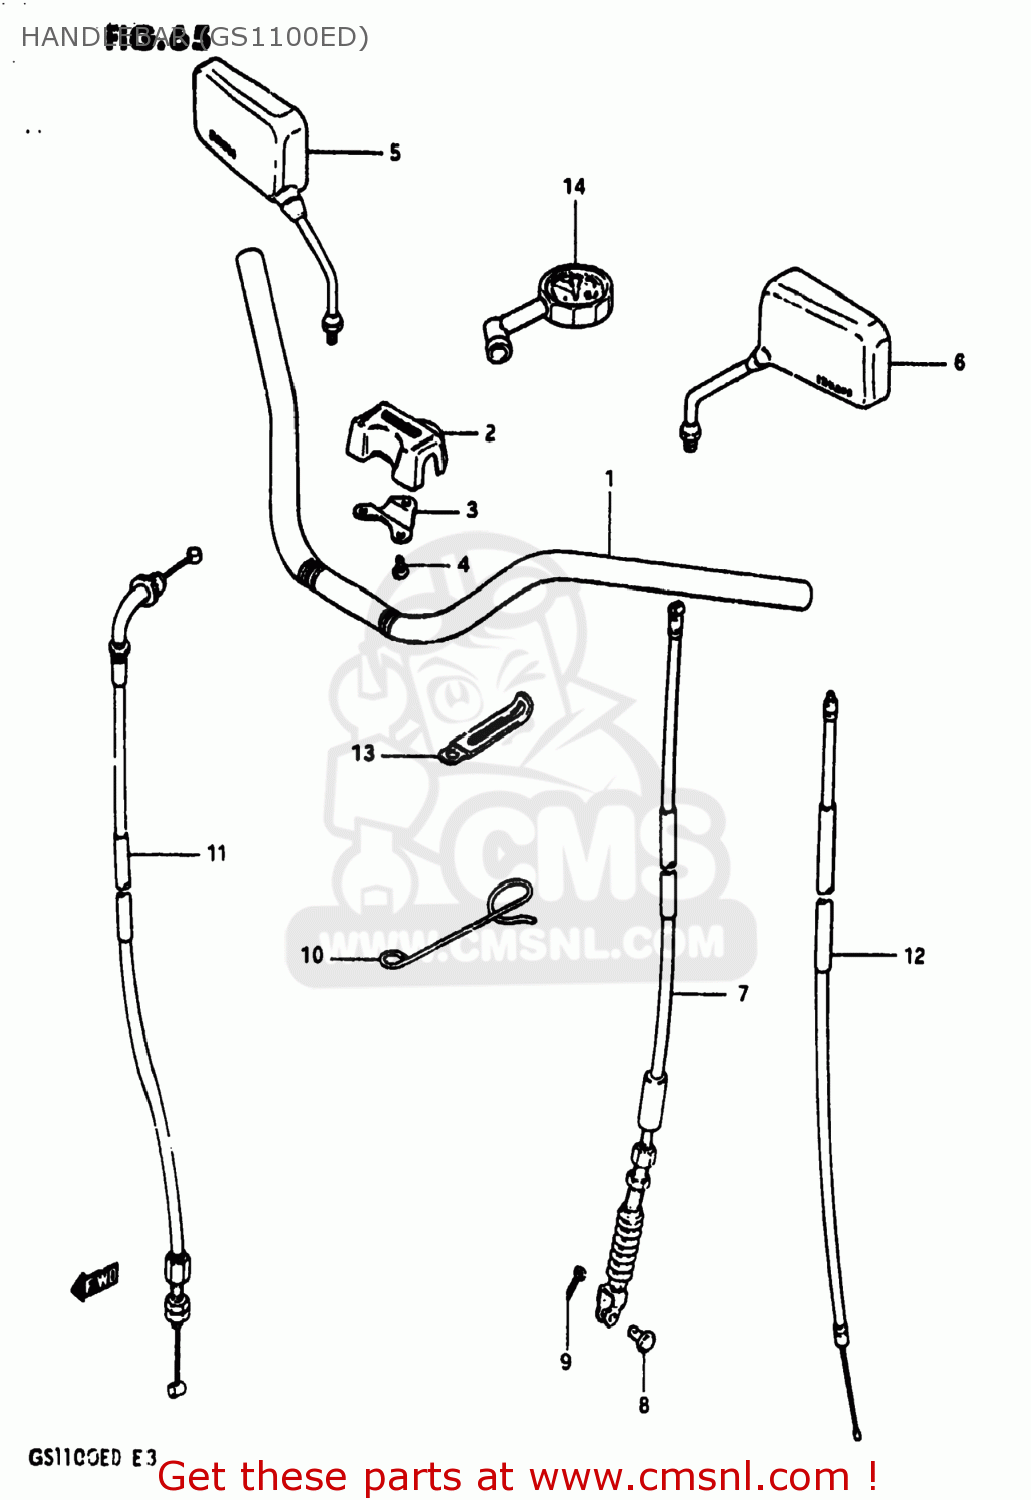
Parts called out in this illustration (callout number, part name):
1	HANDLEBAR
2	COVER,STEERING HEAD
3	BRACKET,STEERING HEAD
4	SCREW
5	MIRROR ASSEMBLY,REAR VIEW
6	MIRROR ASSEMBLY,REAR VIEW
7	CABLE ASSEMBLY,CLUTCH
8	PIN(L:15)
9	PIN
10	GUIDE,CLUTCH CABLE
11	CABLE ASSEMBLY,THROTTLE
12	CABLE ASSEMBLY,STARTER
13	CLAMP
14	GAUGE ASSY,AIR PRESSURE
